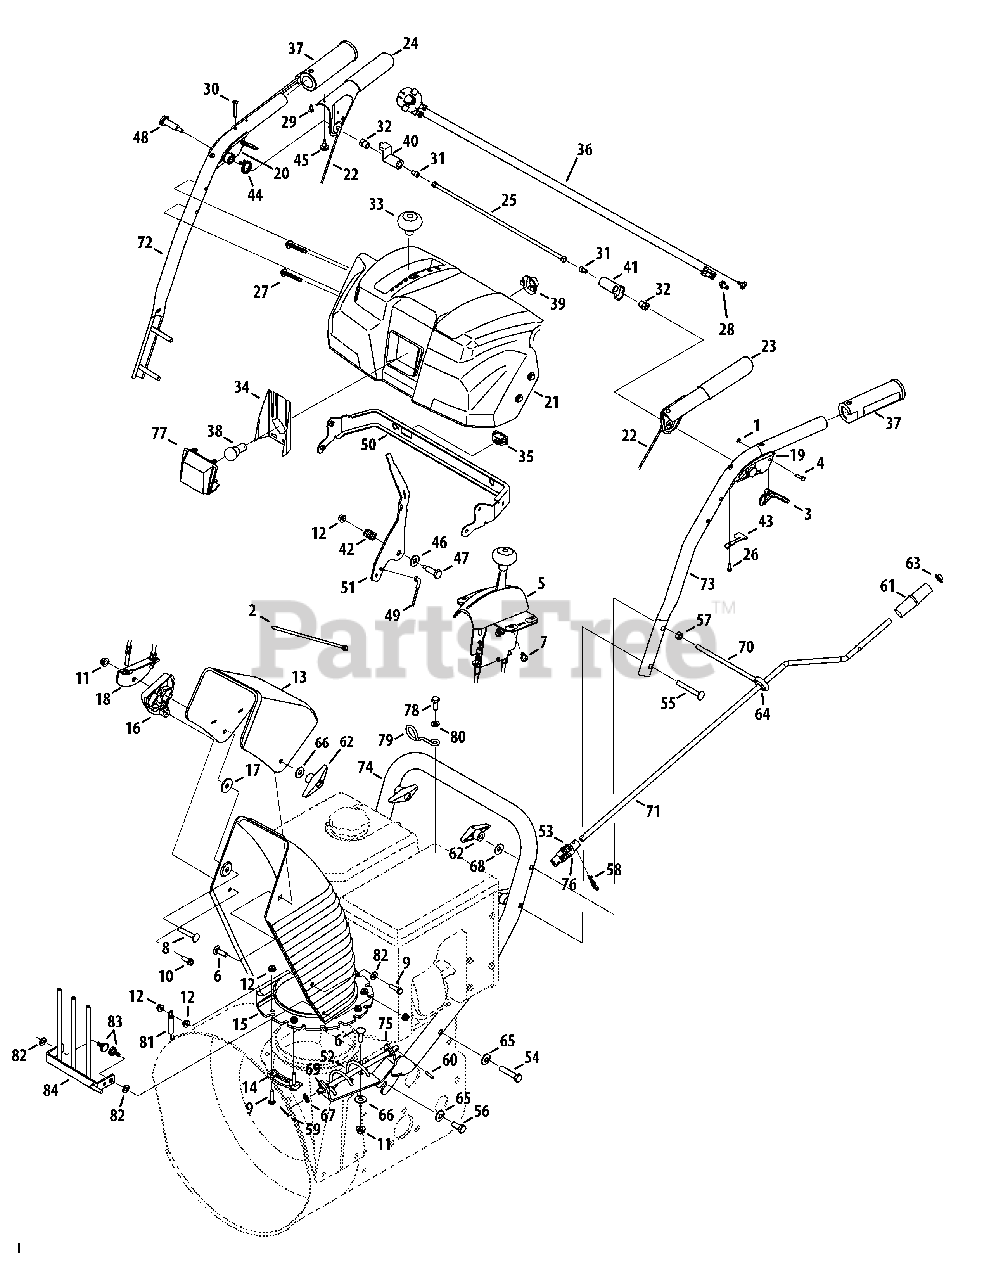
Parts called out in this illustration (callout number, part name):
2	Cable Tie
3	Trigger Lock
5	Chute Control Assembly
6	Carriage Screw, 5/16-18 x 1.0
7	Screw, 1/4-15 x .50
8	Carriage Screw, 5/16-18 x 1.75
9	Hex Screw 1/4-20 x 1.0
10	Screw, 1/4-15 x .750
11	Flange Lock Nut 5/16-18
12	Flange Lock Nut 1/4-20
13	Upper Chute, 6.0
14	Chute Flange Keeper
15	Lower Chute
16	Cbl. Guide, Chute Tilt
17	Flat Wash, .344 x 1.125 x .12
19	Handle Assembly, LH
20	Handle Assembly, RH
21	Handle Panel
22	Cable Ass’y, Auger/Drive
23	Engagement Handle, LH
24	Engagement Handle, RH
25	Clutch Lock Rod Assembly
26	Screw, #8-16 x .50
27	Screw, 1/4-20 x 1.625
28	Hex Screw, 1/4-20 x .5
29	Screw, #10-16 x .625
30	Screw, #10-24 x 1.375
31	Screw, 1/4-20 x .50
32	Nut, Hex, 1/4-20
33	Shift Knob
34	Lens Lable
35	Heated Grip Switch
36	Wire Harness
37	Heated Grip
38	Lamp, 12.8V
39	Light Socket
41	Clutch Lock Cam
42	Compression Spring
43	Clutch Lock Spring
44	Torsion Spring, .8156 ID x .3038
45	Rubber Bumper
46	Flat Washer, .385 x .87 x .06
47	Screw, Shldr., .374 x 1.05
48	Screw, Shldr., .437 x 1.345
49	Clutch Cable
50	Panel Bracket
52	Chute Crank Assembly
53	Joint Block Assembly
54	Hex Screw, 3/8-16 x 2.00
55	Carriage Screw, 5/16-18 x 2.5
56	Screw, Hex, 3/8-16 x 1.00
57	Nut, Hex, 5/16-18
58	Internal Cotter Pin
59	Internal Cotter Pin
60	Spring Pin, .156 dia. x .875 Lg.
61	Knob, Crank
62	Knob, Wing Nut, 5/16-18
63	Push Cap, 3/8
64	Rubber Grommet
65	Bell Wash, .375 x .87 x .063
66	Flat Washer, .349 x .879 x .063
67	Flat Wash, .375 x .738 x .063
68	Wash, Bell, .34 x .872 x .06
69	Plastic Bushing, .38 ID
70	Eye Bolt, .70 Dia.
71	Chute Rod, .375 Dia. x 29.72
72	Handle, Upper, RH
73	Handle, Upper, LH
74	Handle, Lower
75	Chute Crank Bracket
76	Roll Pin, 3/16 Dia. x 1.100
78	Hex Screw, M8-1.25
79	Cable Guide
80	Flat Washer, .330 x .630 x .0635
81	Spring, Extension, .38 OD x 2.50
82	Flast Washer, .25 x .63 x .052
83	Shoulder Screw, .375 Dia. x .181
84	Guard Assembly, 6" Dia. Chut
